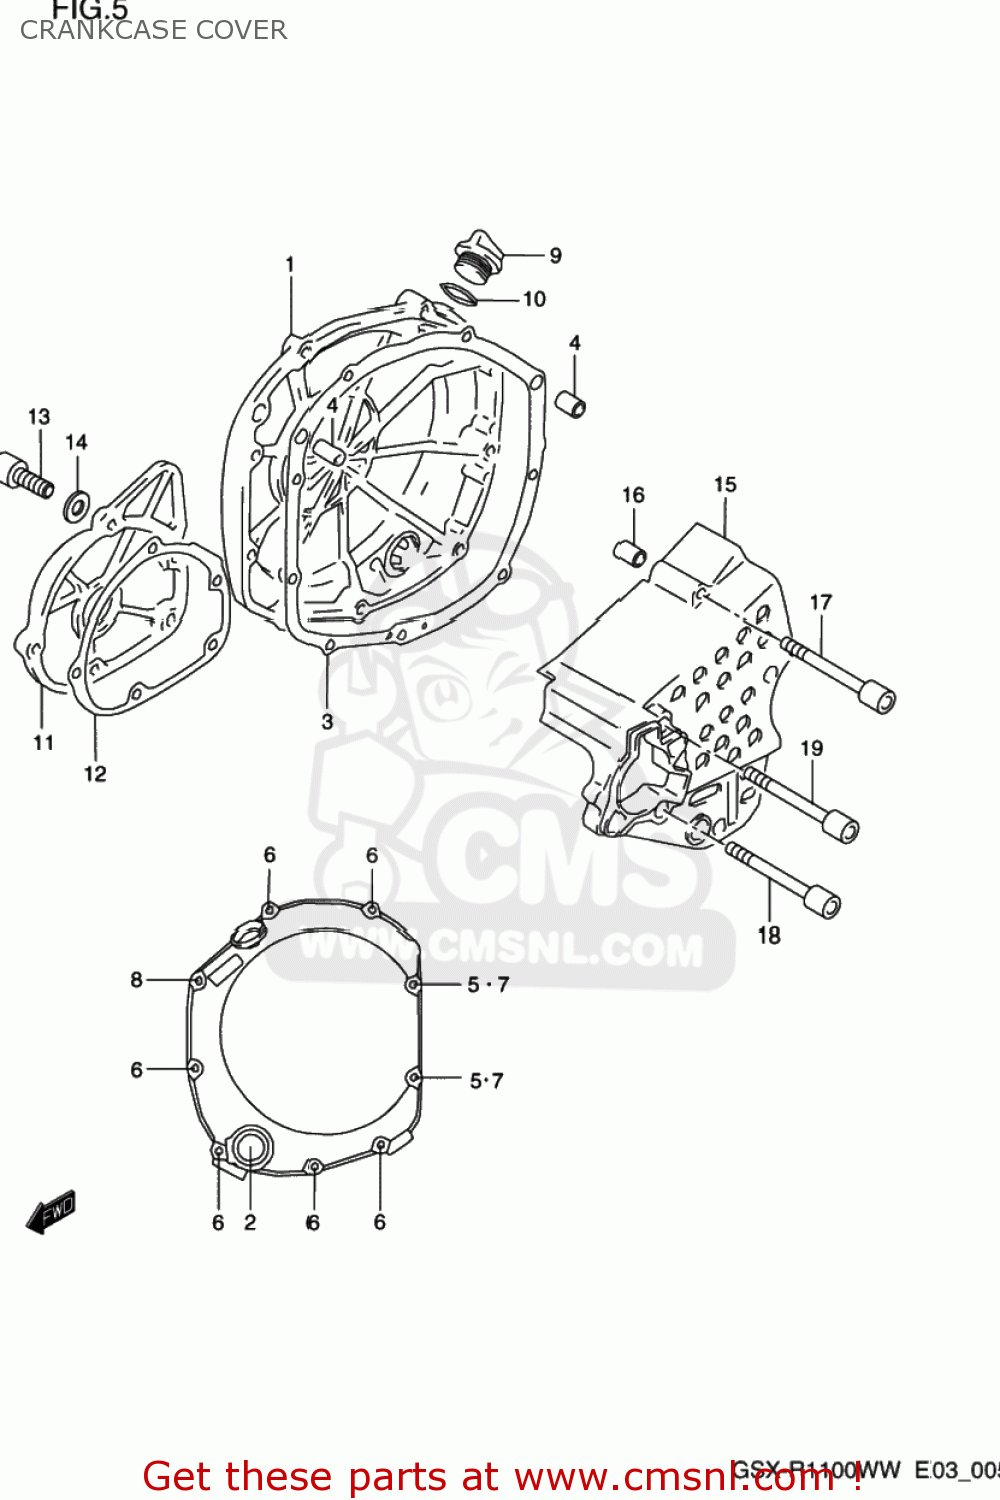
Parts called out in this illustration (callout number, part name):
1	COVER,CLUTCH
2	LENS,OIL LEVEL CHECK
3	GASKET,CL COVER (NAS)
4	PIN
5	GASKET(5.8X11X1.2) (NAS)
6	BOLT
7	BOLT
8	BOLT
9	PLUG
10	O RING(D:3.1,ID:16.8)
11	CAP
12	GASKET,SIGNAL GEN COVER
13	BOLT
14	GASKET(5.8X11X1.2) (NAS)
15	COVER,ENGINE SPROCKET
16	PIN
17	BOLT
18	BOLT
19	BOLT
